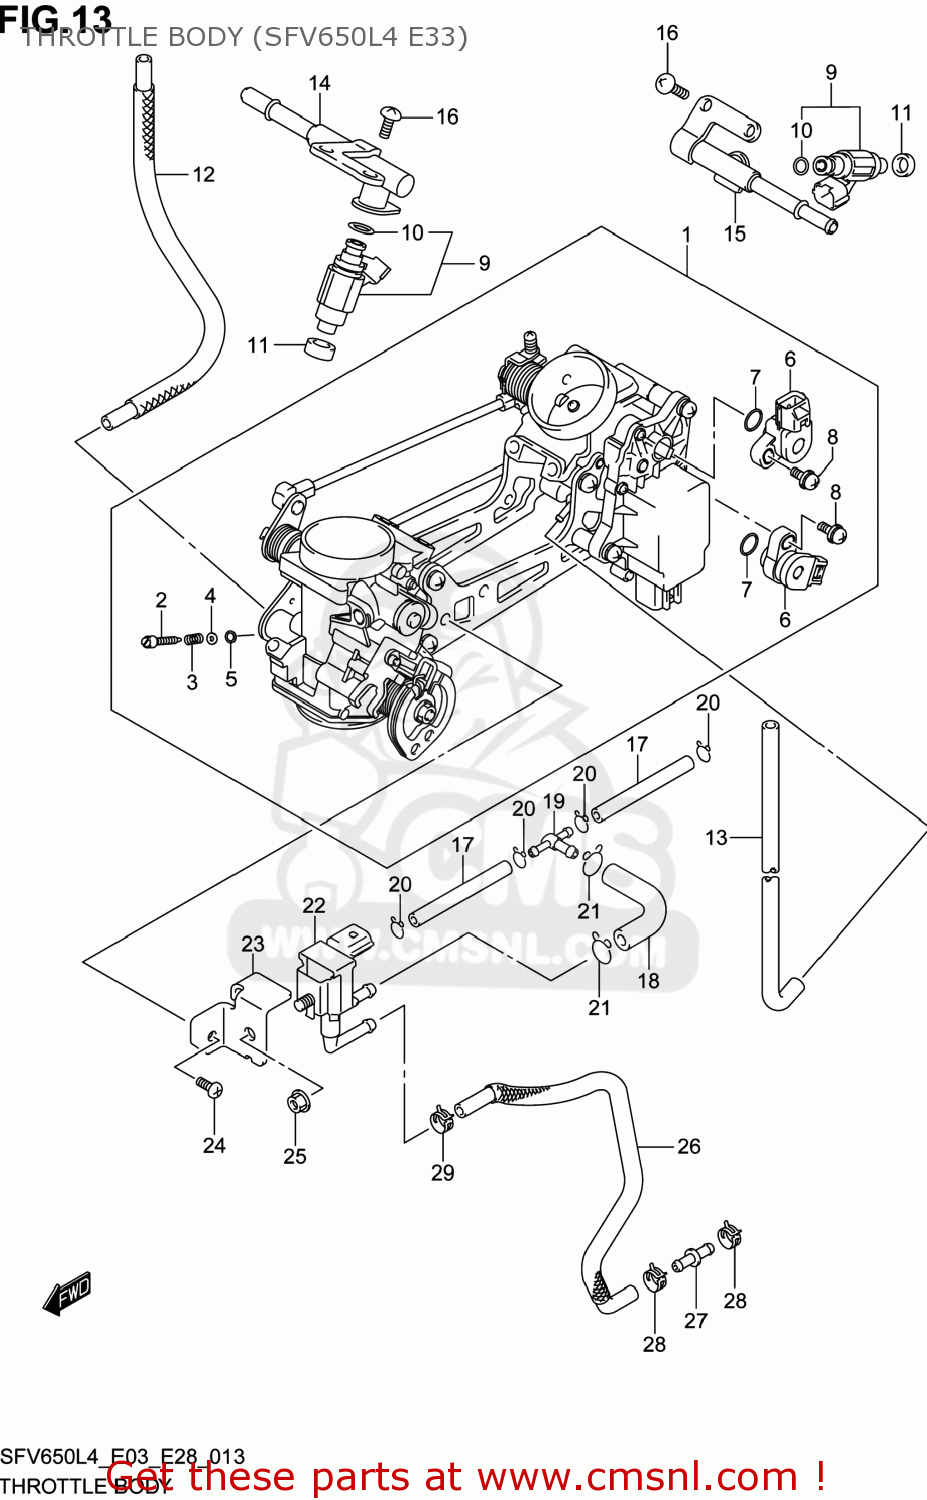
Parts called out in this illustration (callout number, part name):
1	BODY ASSY,THROTTLE
2	SCREW
3	SPRING,THROTTLE SCREW
4	WASHER
5	O RING,PILOT AIR SCREW
6	SENSOR
7	O RING
8	SCREW
9	INJECTOR ASSY
10	O-RING
11	SEAL
12	HOSE
13	HOSE
14	DELIVERY PIPE
15	DELIVERY PIPE
16	SCREW
17	HOSE
18	HOSE
19	NIPPLE
20	CLIP
21	CLIP
22	VALVE,CANISTER PURGE
23	BRACKET
24	SCREW
25	NUT
26	HOSE,PURGE VALVE
27	JOINT
28	CLIP
29	CLIP
